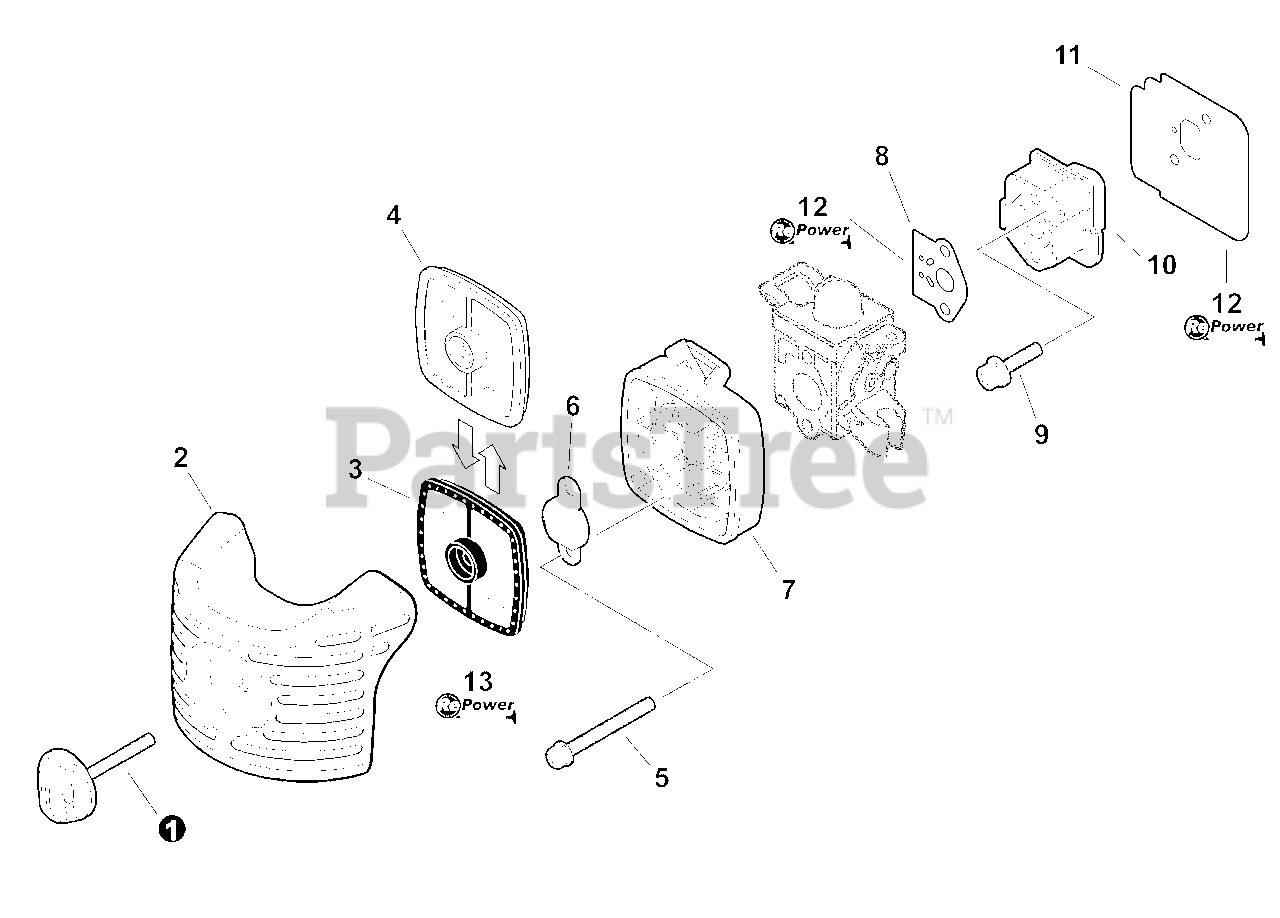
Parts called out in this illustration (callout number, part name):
1	THUMBSCREW
2	COVER, AIR FILTER
3	FILTER, AIR - DOUBLE LAYER
4	FILTER, AIR - SINGLE LAYER
5	SCREW - 5×65
6	PLATE, PREVENT
7	CASE, AIR FILTER
8	GASKET, INTAKE
9	INSULATOR, INTAKE
10	SCREW - 5×25
11	SHIELD, INTAKE
12	GASKET KIT
13	RePower FILTER KIT
13	RePower TUNE-UP KIT
